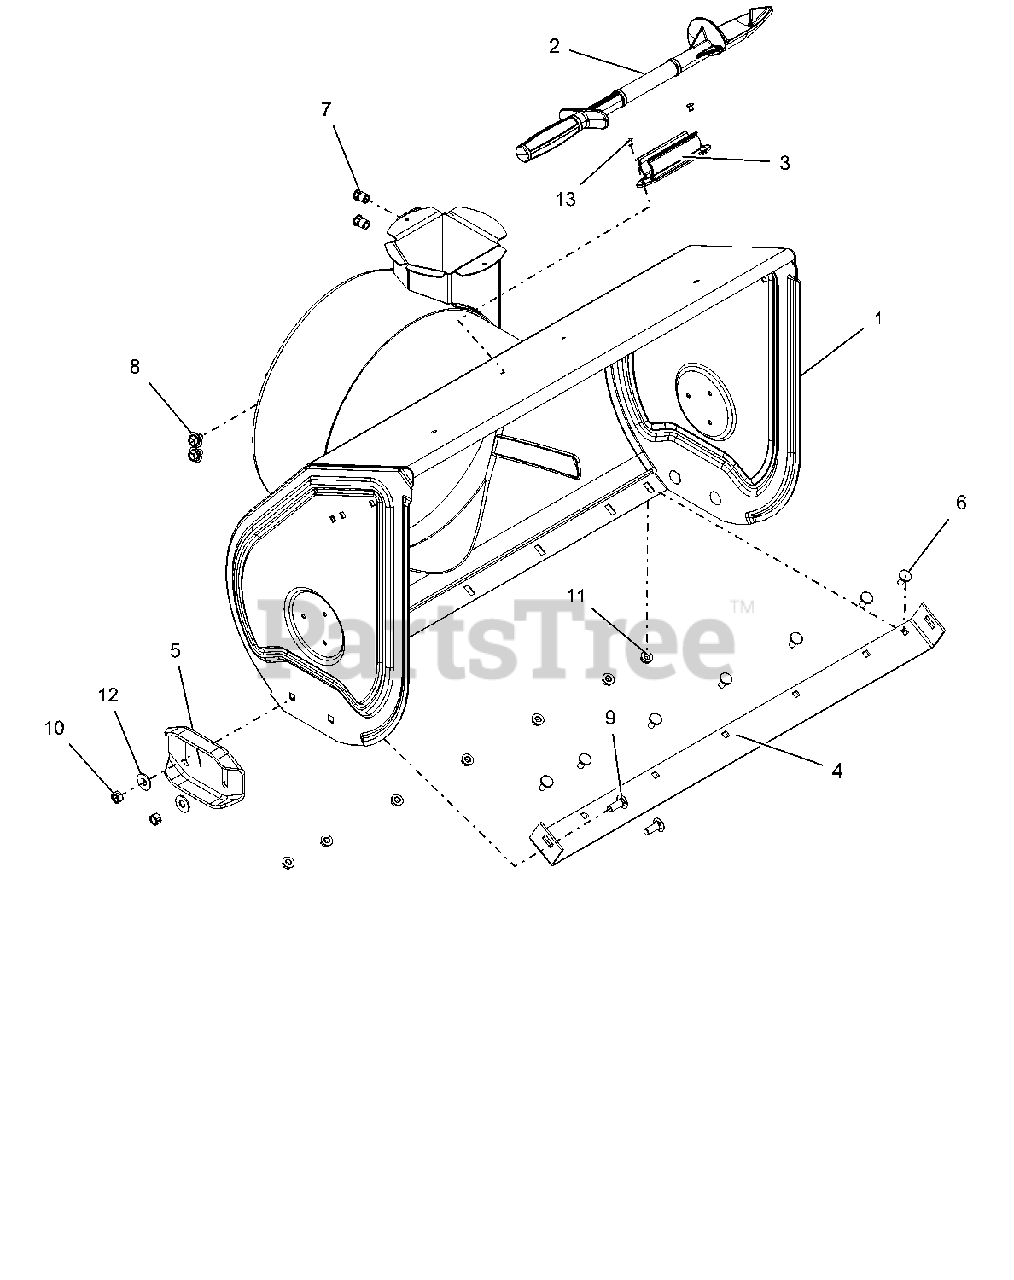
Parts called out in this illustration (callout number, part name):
1	BLOWER HOUSING W/DECAL 30"
2	DEVICE, SNOW CLEAN OUT
3	MOUNT, SNOW CLEAN OUT
4	BLADE, SCRAPER-30"
5	SKID SHOE, REVERSIBLE - ORANGE
6	BOLT, MODIFIED HEAD CARRIAGE
7	NUT, THREADED INSERT .38-16
8	SCR-TAP.31-18X.50 HWH TR YWZ
9	@BLT-RDHDSHSQNK.38-16X1.0 G5YZ
10	@NUT-LK-CTR .38-16 YWZC
11	@NUT-LK-TOP-FLG .31-18 YWZC
12	@WSHR-FL-STL.438X1.00X.083 YWZ
13	RVT-POP .187 YZ
